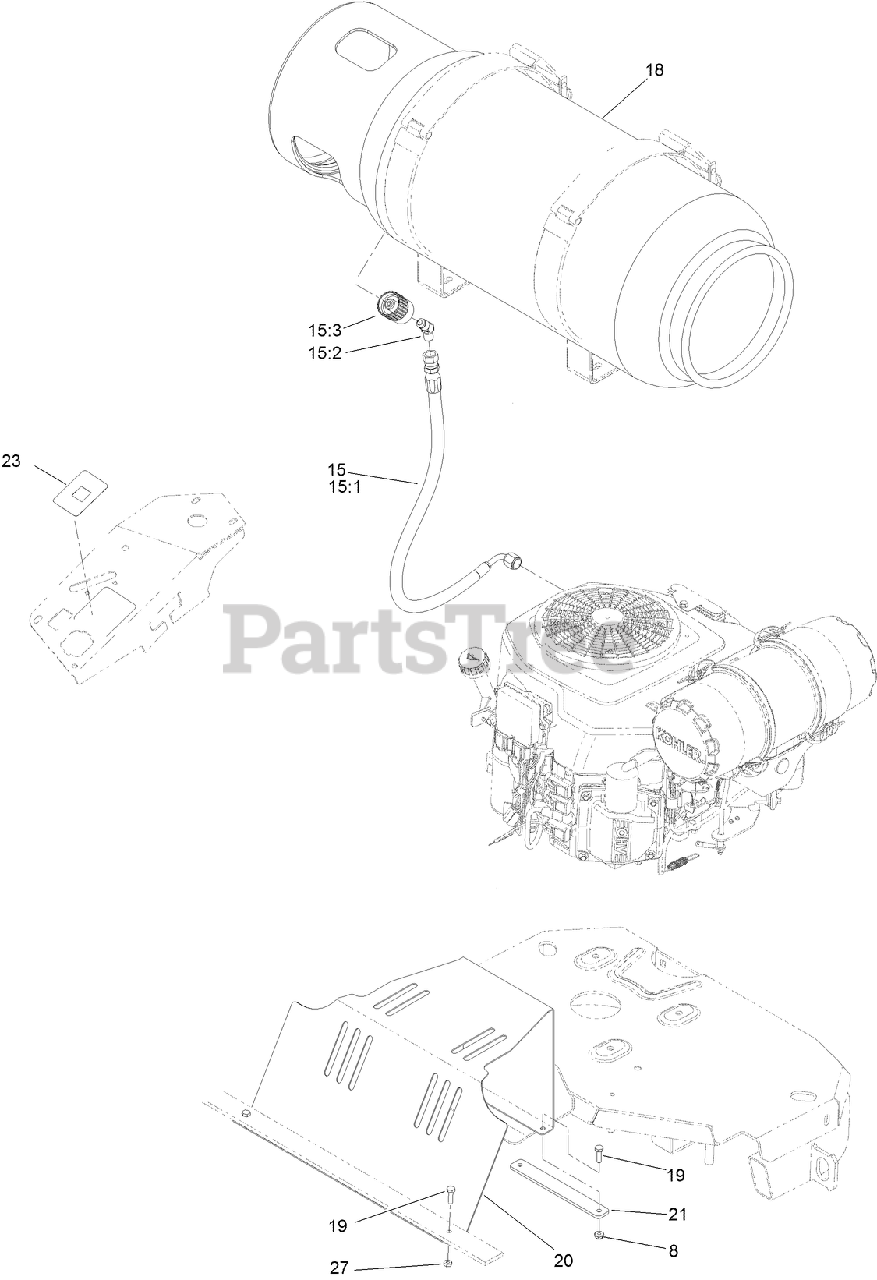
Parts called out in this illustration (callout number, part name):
8	NUT-HF
15	LPG HOSE ASM
15:1	LPG FUEL HOSE ASM
15:2	ELBOW-45 DEG
15:3	CONNECTOR-LPG TANK, LH THREAD
18	TANK-LPG
19	SCREW-HH
20	SHEILD-FAN
23	DECAL-METER, HOUR
27	NUT-JAM
